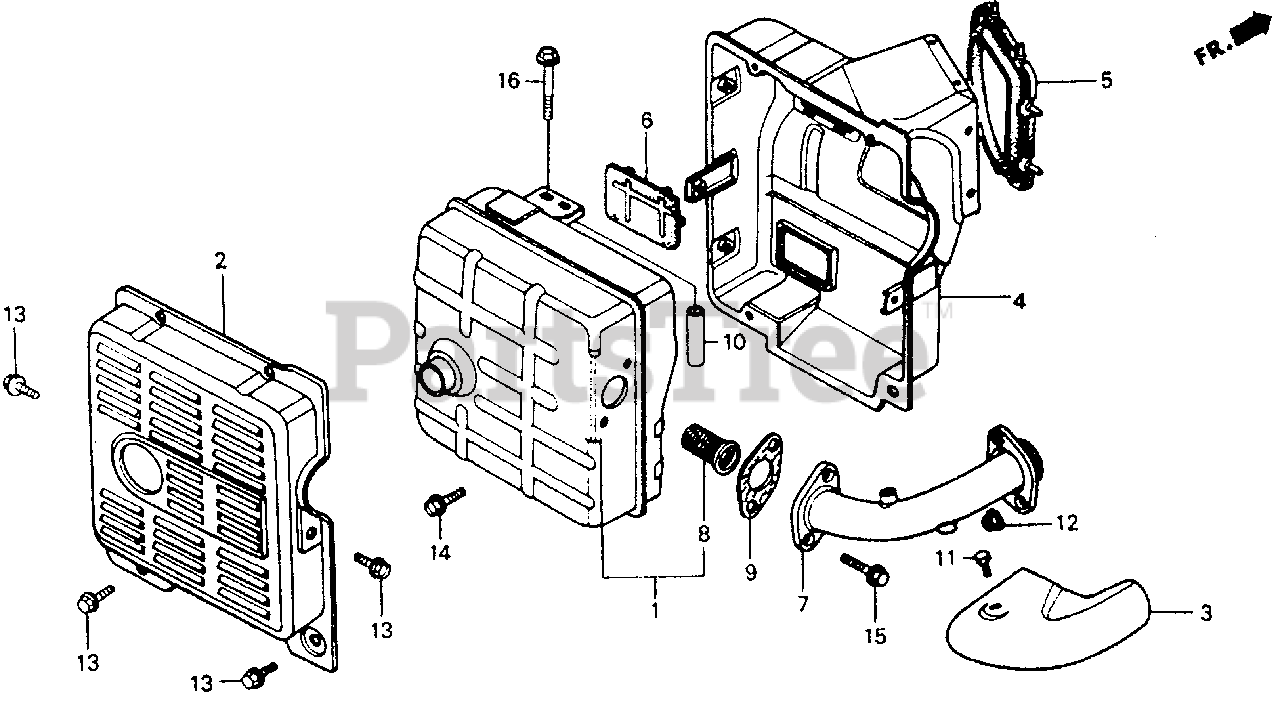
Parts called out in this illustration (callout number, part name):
1	MUFFLER (NOT AVAILABLE)
2	PROTECTOR, MUFFLER (OUTER)
3	PROTECTOR, EX. PIPE
4	PROTECTOR, MUFFLER (INNER)
5	RUBBER, PROTECTOR (INNER)
6	SEAL, MUFFLER PROTECTOR
8	ARRESTER, SPARK
9	GASKET, EX. PIPE
10	COLLAR, MUFFLER
11	BOLT, HEX. (6X8)
12	NUT, FLANGE (8MM)
13	BOLT, FLANGE (6X10)
14	BOLT, FLANGE (8X16)
15	BOLT, FLANGE (8X20)
16	BOLT, FLANGE (8X45)
